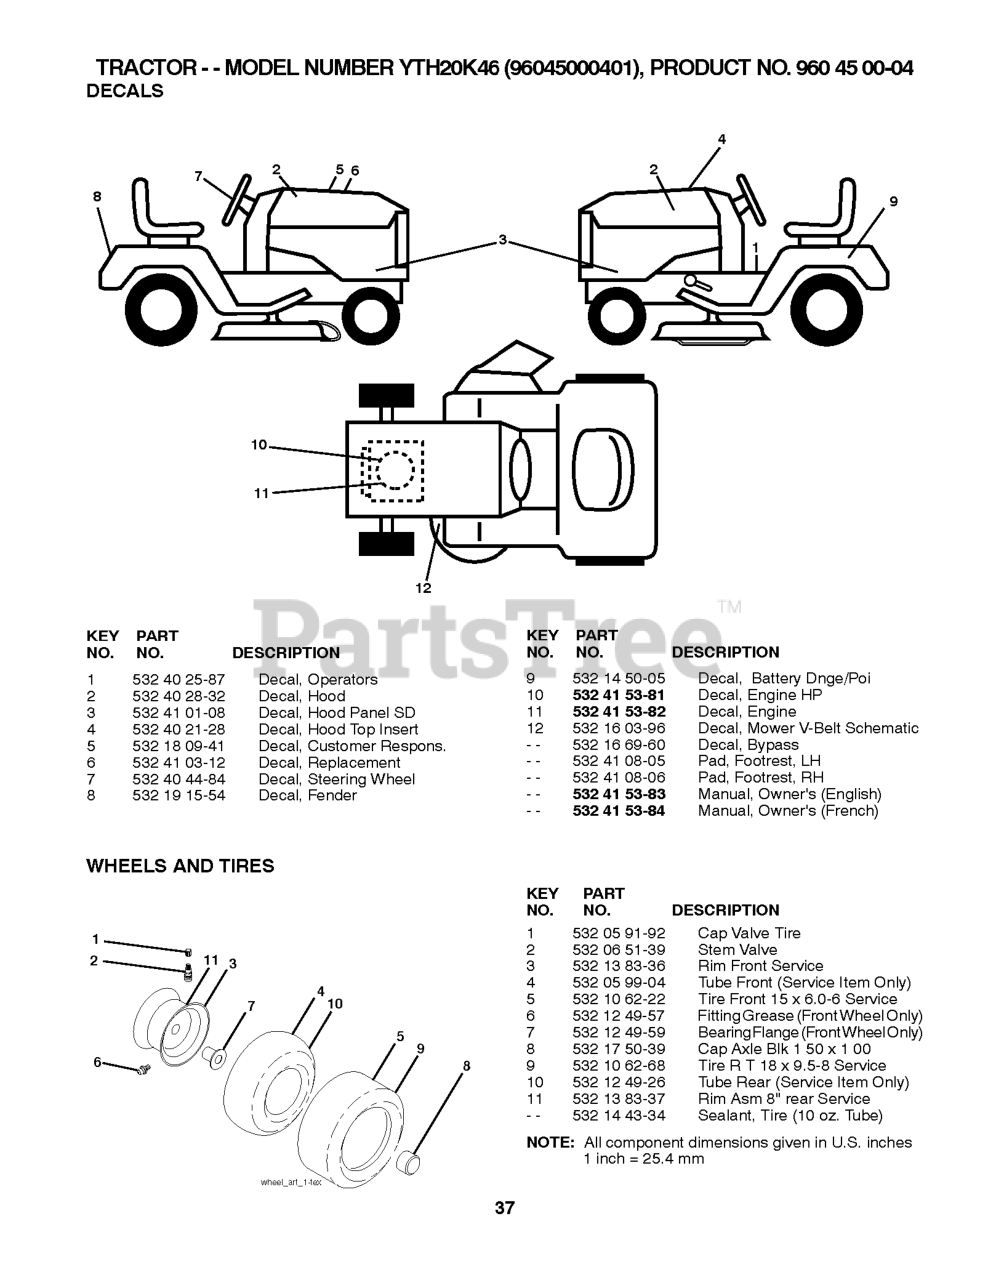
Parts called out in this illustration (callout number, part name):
1	DECAL.OPER/WRNG.TEX.CR
2	DECAL.HOOD.NAMELOGO.HUSQ
3	DECAL, HOOD PANEL SD
4	DECAL.HOOD.TOP.INSERT.
5	DECAL HOOD CUST. RESP.
6	DECAL REPLACEMENT
7	DECAL.WHEEL.STRG.LGN.H
8	DECAL.FENDER
9	DECAL BTRY SYMBOLS
10	DECAL.ENGINE.21HP.KOHL.HUSQ
11	DECAL.ENG.KOHL.HUSQ(2011337)
12	DECAL V BELT SCHEMATIC
